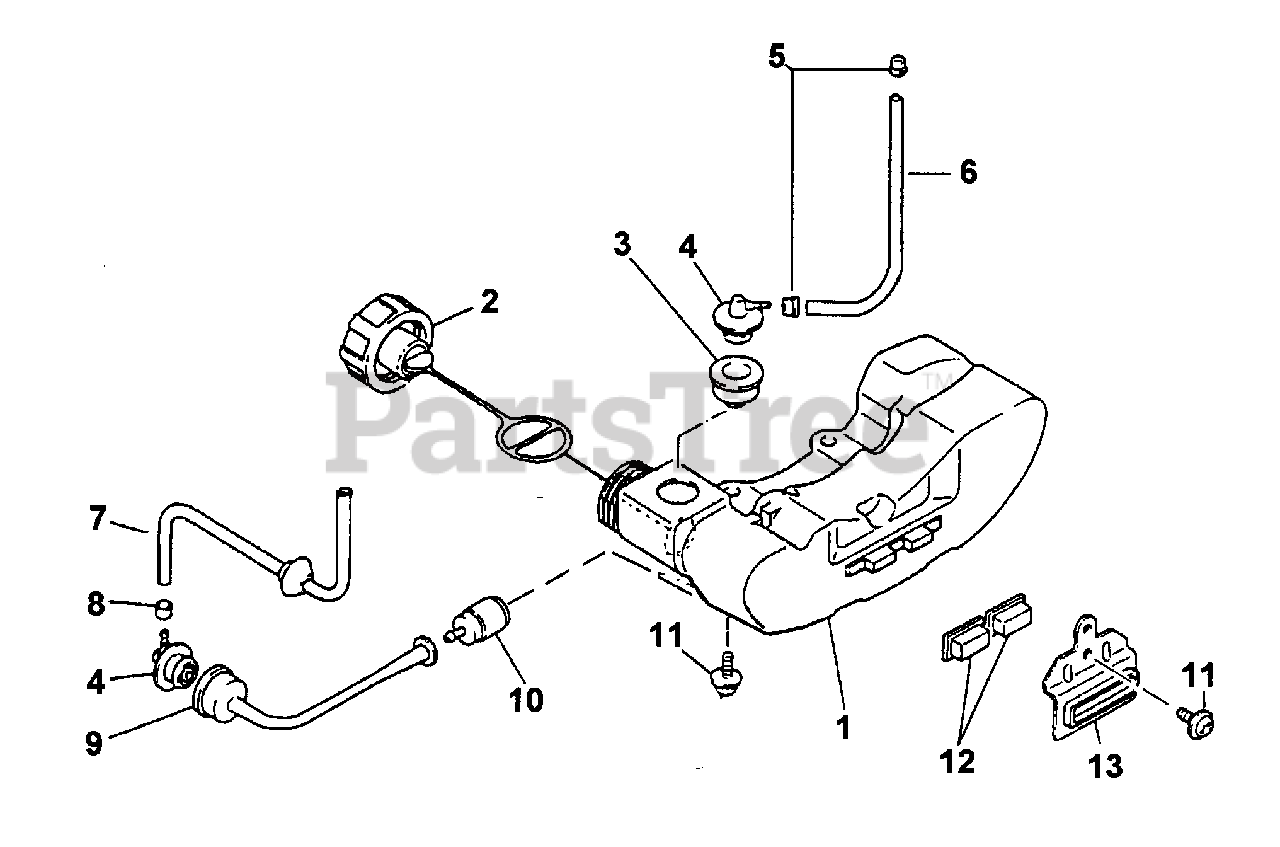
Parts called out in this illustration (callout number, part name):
1	FUEL TANK ASSY.
2	CAP ASSY.,TANK
6	LINE, FUEL
7	LINE, FUEL
9	HOSE, SUCTION
10	FILTER, FUEL
11	SCREW & WASHER
13	BRACKET, TANK
